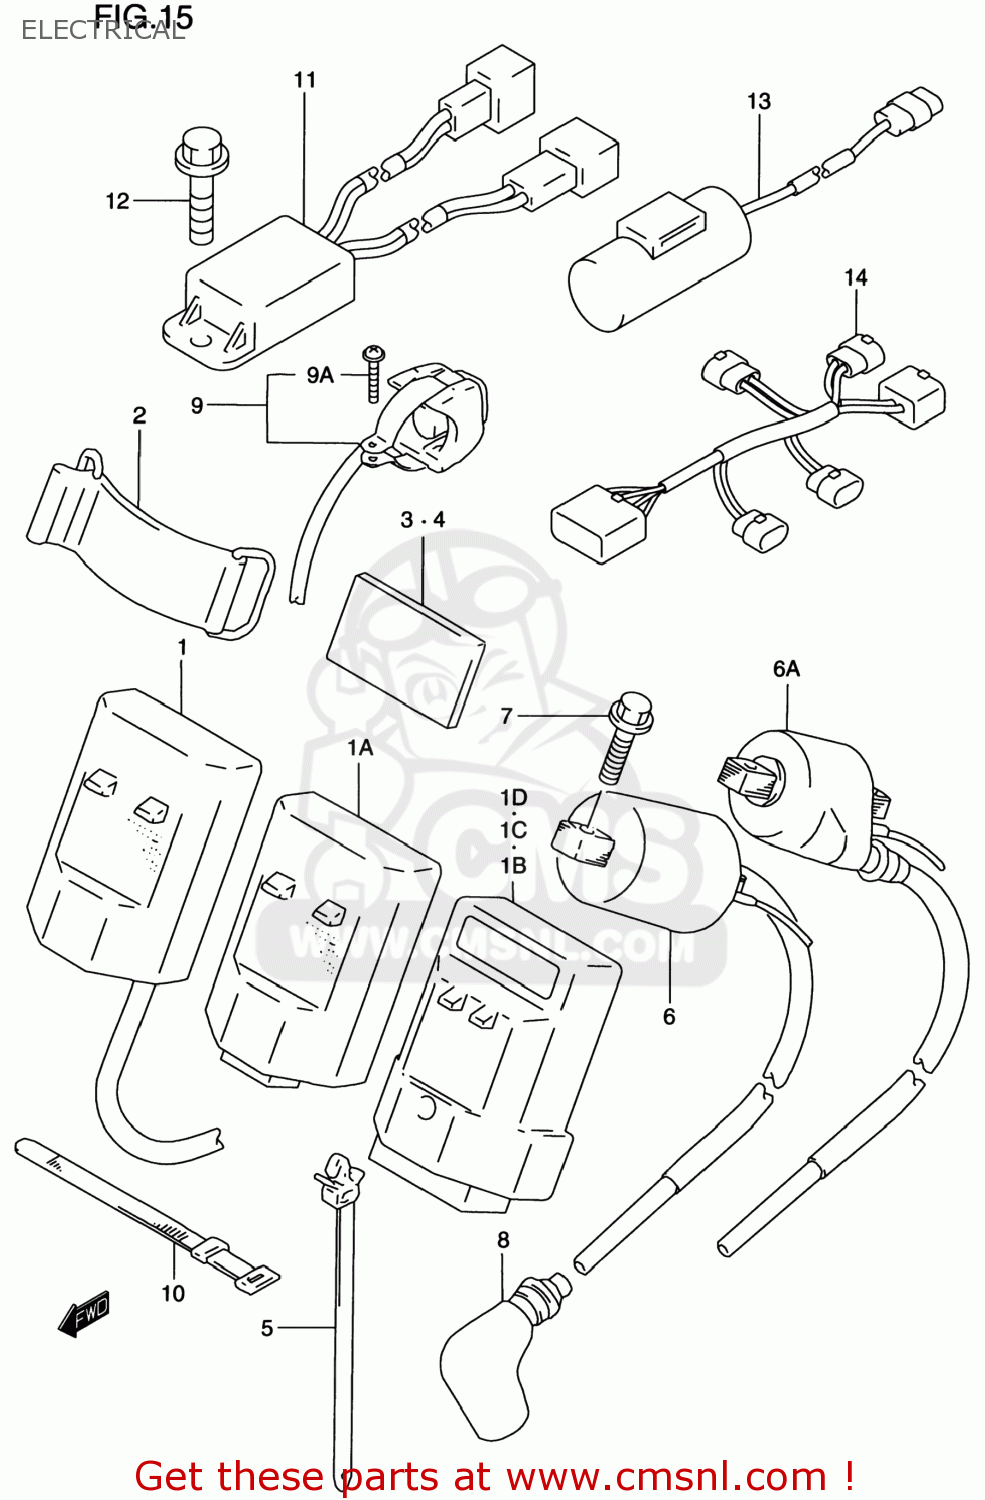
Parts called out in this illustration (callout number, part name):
1	CDI UNIT
1A	CDI UNIT
1B	CDI UNIT
1C	CDI UNIT
1D	CDI UNIT
2	BAND(L:65)
3	PROTECTOR(170X95X3.0)
4	PROTECTOR(170X95X3.0)
5	CLAMP(L:90)
6	COIL ASSY,IGNITION
6A	COIL ASSEMBLY,IGNITION
7	BOLT
8	CAP,SPARK PLUG
9	SWITCH ASSY,ENGINE STOP
9A	SCREW
10	CLAMP(L:120)
11	RECTIFIER ASSY
12	BOLT
13	CONDENSER ASSY
14	HARNESS,WIRING
